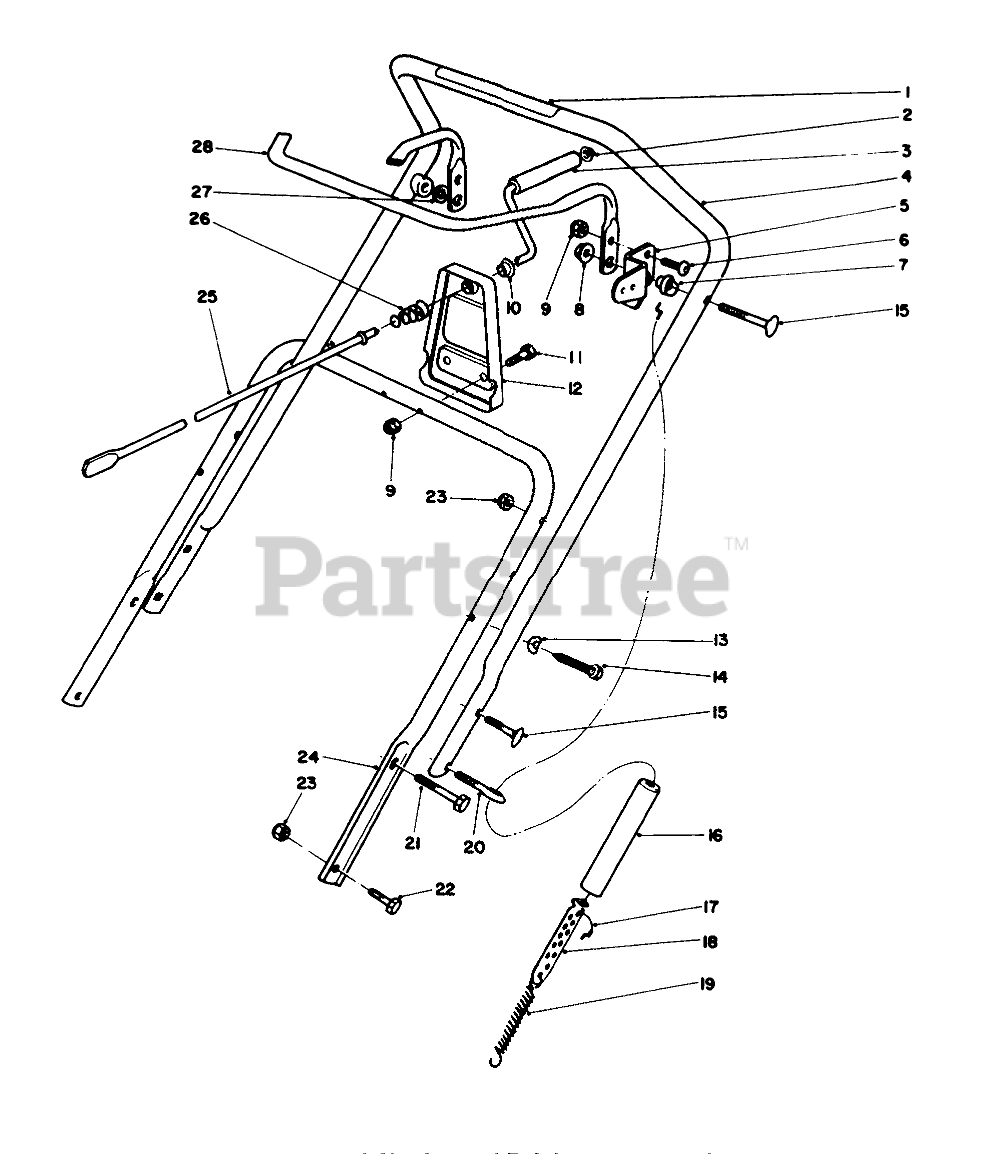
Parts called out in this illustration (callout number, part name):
1	DECAL - ROTOR DRIVE
2	RETAINER-PUSH ON
3	Grip-Rod
4	Upper Handle Assembly (Incl. ref. #1, Model 38185)
5	Arm-Clutch Cable
6	SCREW-HSBH
7	SPACER-BAR, CONTROL
8	NUT-LOCK, CAP
9	NUT-LOCK, NI
10	Bushing
11	SCREW-HH
12	Support-Crank
13	WASHER
14	SCREW
15	SCREW
16	COVER-SPRING
17	CABLE-CLUTCH
18	ADJUSTER-CABLE
19	SPRING-EXTENSION
20	BOLT-EYE
21	SCREW-HH
22	SCREW-HH
23	NUT-LOCK, NI
24	Handle-Lower (Model 38180)
25	ROD-CRANK, CHUTE
26	SPRING-COMPRESSION
27	WASHER
28	Bar-Control
